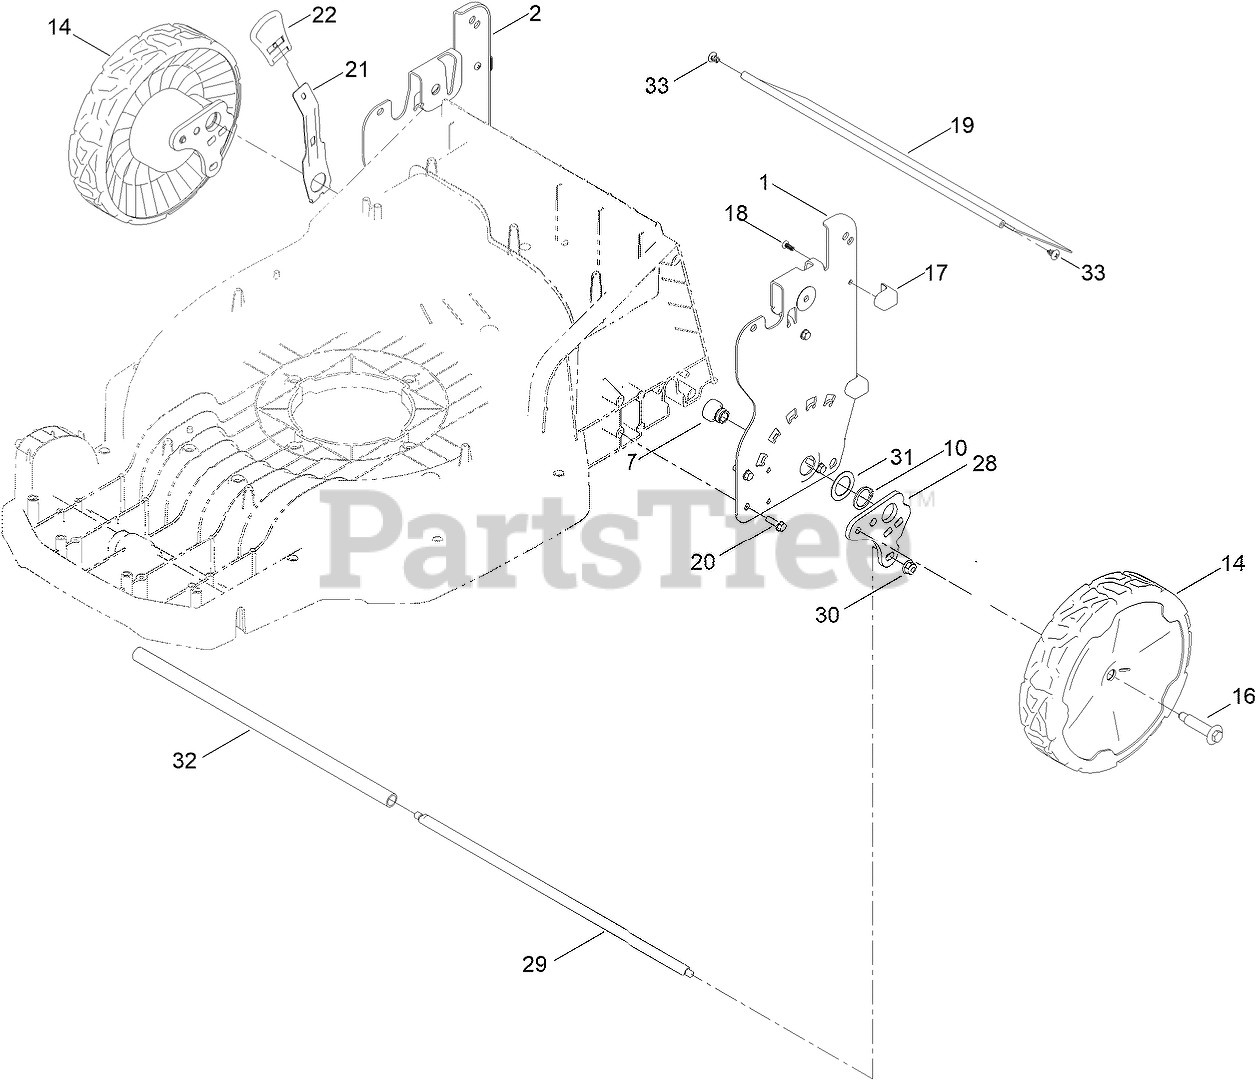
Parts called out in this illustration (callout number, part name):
1	PLATE-HOC, LH
2	PLATE-HOC, RH
7	RETAINER-BEARING, HOC
10	RING-RETAINING
14	ASM-9.65" WHEEL, BUSHINGS
16	WHEEL BOLT
17	PAD-SMART STOW
18	SCREW-PLASTITE
19	SHIELD-TRAILING
20	SCREW-HWH
21	ARM-SPRING
22	KNOB-HOC
28	BRKT-PIVOT, REAR
29	ROD-CONNECTING, REAR
30	NUT-HF, NI
31	WASHER-FLAT
32	ROLLER-STRIPER
33	SCREW-THD
